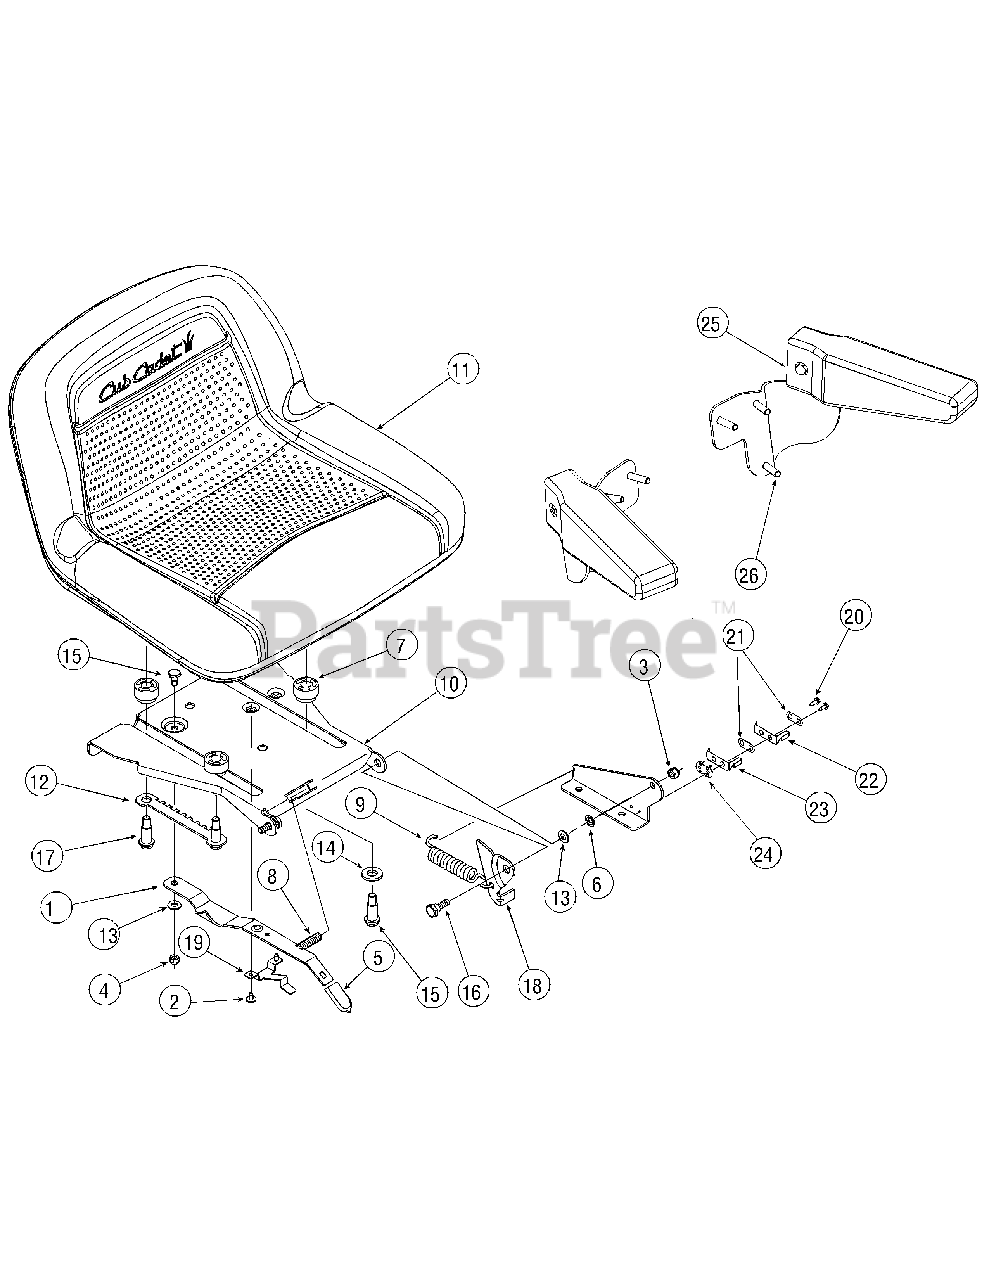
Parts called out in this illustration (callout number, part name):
2	Screw, #10-16, 0.375
3	Nut, Nylon Lock, 5/16-18, Gr5
4	Nut, Nylon Lock, 1/4-20
5	Grip, Seat, Adjustment (Yellow)
6	Nut, Speed, .3125 ID
7	Spacer, Seat, Adjustment
8	Spring, Compression .41 OD x 1.50
9	Spring, Extension, .80 Dia x 4.6
12	Selector, Seat, Adjustment
13	Washer, Flat, .344 x .688 x .065
14	Washer, Flat, .531 x 1.062 x .134
15	Screw, Shoulder, .340 x .285, 1/4-
16	Shoulder, Screw .437 x .286 Lg
17	Screw, Shoulder, .50 x.925, 3/8-16
18	LH Bracket, Seat Lift
18	RH Bracket, Seat Lift
19	Stop, Seat, Adjustment
20	Screw, #8-18 x .50
21	Plate, Insulator
22	Spring Switch, Inner
23	Spring Switch, Outer
24	Plate, Insulator Boss
25	Armrests (Includes two armrests)
26	Screw, 5/16-18, .75
